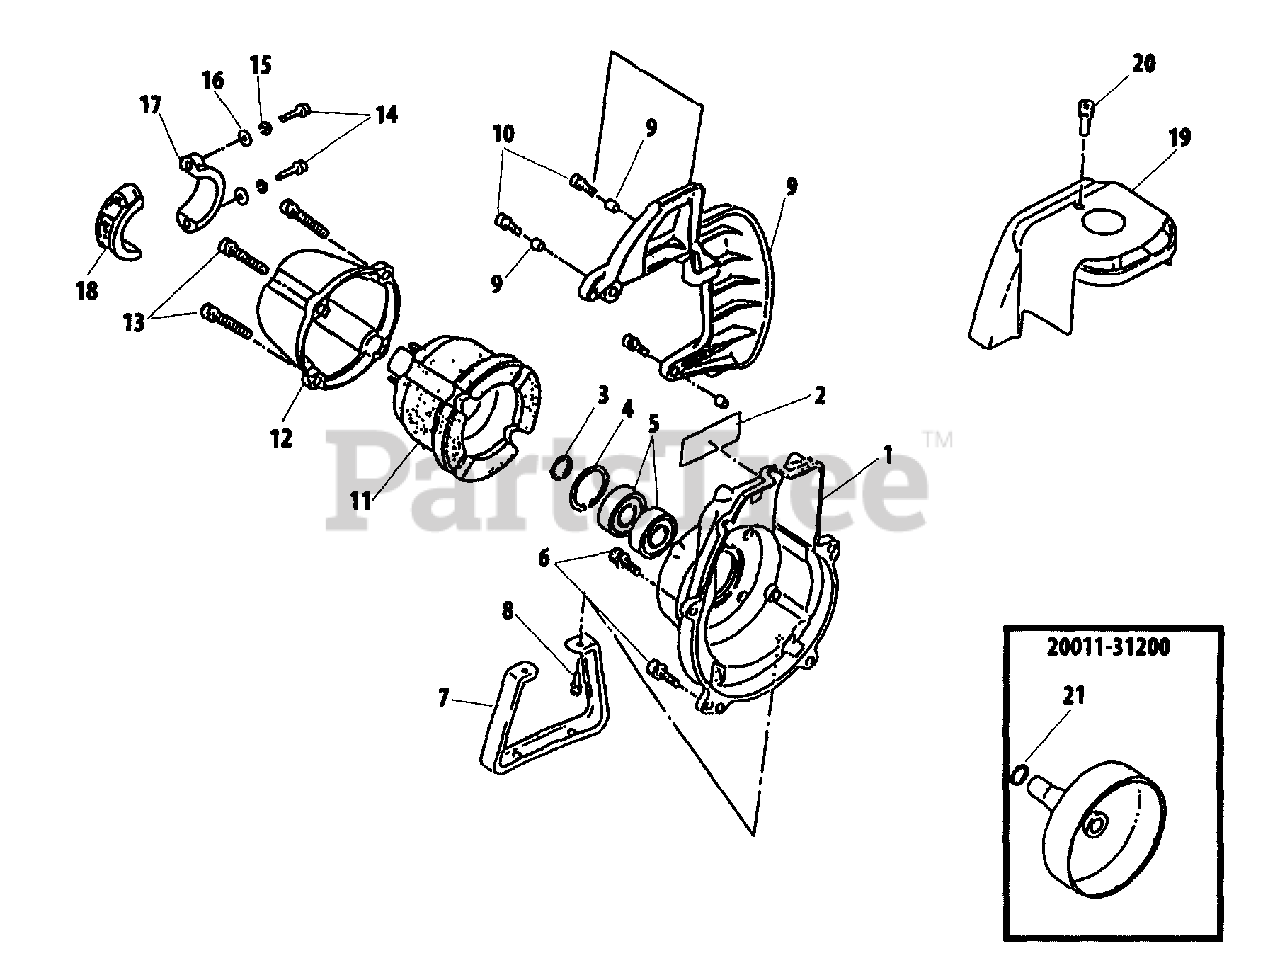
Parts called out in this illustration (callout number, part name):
1	COVER, FAN
2	LABEL, TRADE
3	RING, SNAP
4	RING, SNAP Ø32
5	BEARING, BALL 6002 DDU
6	BOLT M5×20
7	STAND
8	BOLT M5×16
9	GUARD, TOP
10	BOLT M4×16
11	CUSHION, AV
12	CAP, CUSHION
13	BOLT M5×20
14	BOLT 5×25
15	WASHER, SPRING 5
16	WASHER, FLAT 5.5×10×0.8
17	CLAMP - B
18	CLAMP - A
19	COVER, ENGINE
20	BOLT 5×14
21	RING, RETAINING
20011-31200	DRUM, CLUTCH
